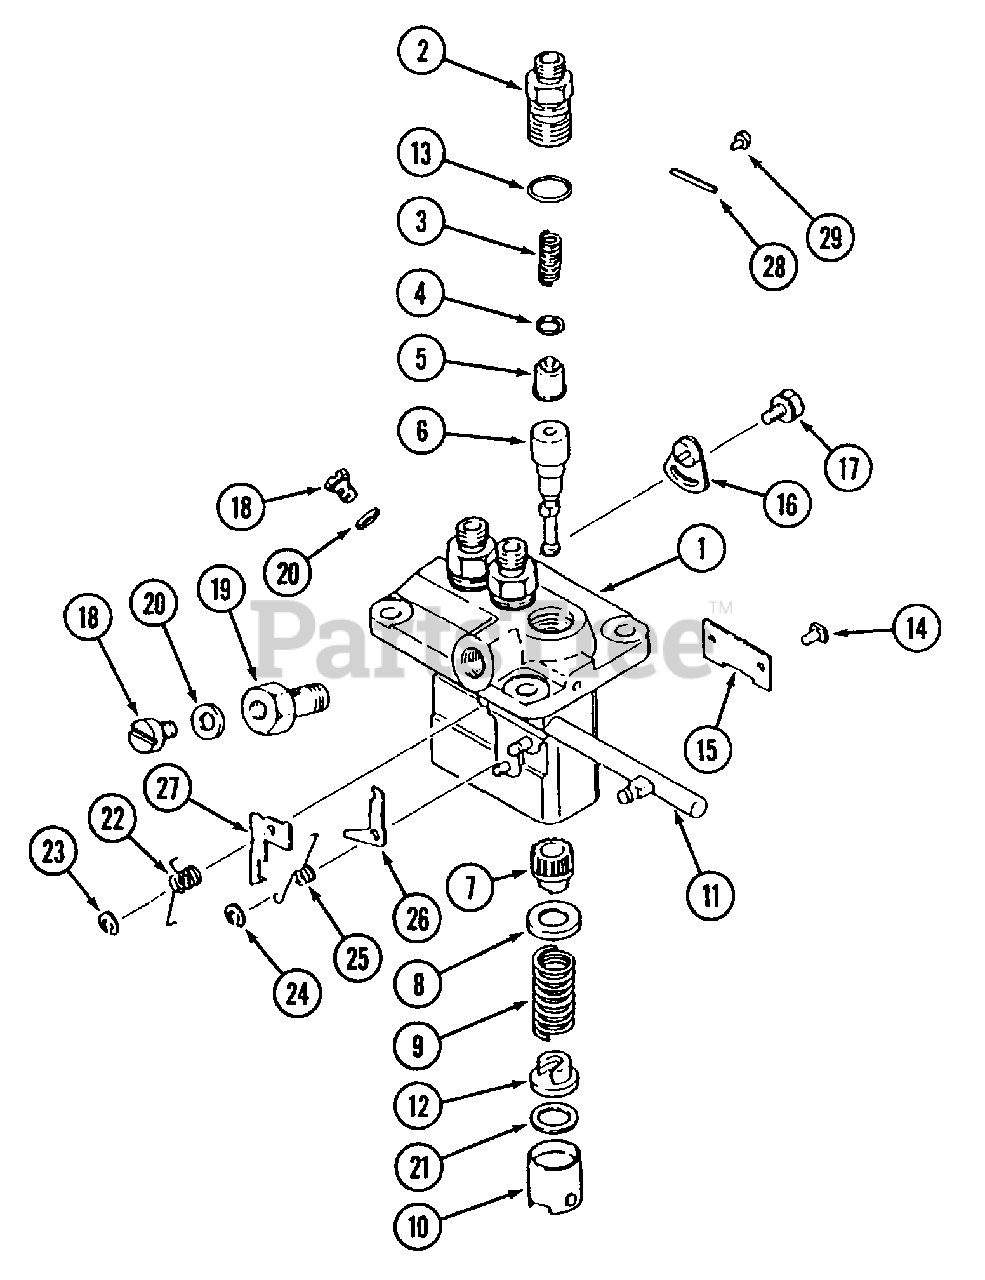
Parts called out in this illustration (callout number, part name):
1	Housing Sub Ass'y., Pump
2	Holder, Delivery Valve
3	Spring, Delivery Valve
4	Gasket, Delivery Valve
5	Valve Sub Ass'y., Delivery
6	Element Sub Ass'y., Pump
7	Sleeve, Control
8	Seat, Spring Upper
9	Spring, Pump Plunger
10	Tappet Ass'y.
11	Pack Ass'y., Control
12	Seat, Spring Lower
13	O-Ring
14	Pin, Tappet Guide
15	Plate
16	Plate, Adjusting
17	Bolt, Washer Hade
18	Screw, Air Bleeder
19	Screw, Hollow
20	Washer, Pipe Union
21	Shim, Plate Tappet t=0.6
22	Spring, Smoke Set
25	Spring Angleich Set
26	Plate, Angleich Set Mark 6
27	Plate, Smoke Set Mark 62
28	Plate, Name
